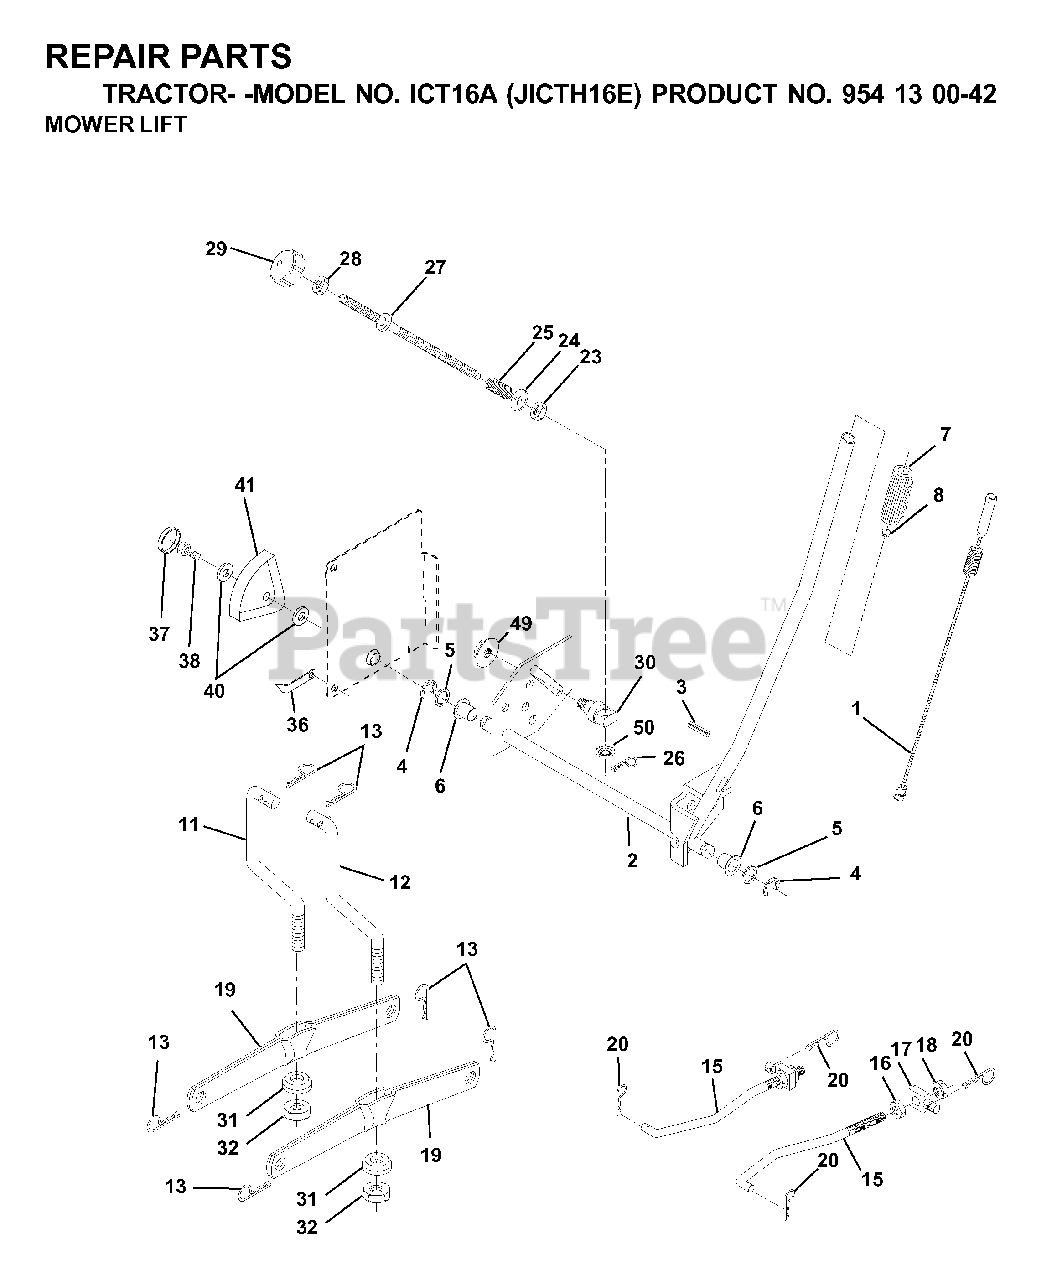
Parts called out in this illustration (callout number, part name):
1	WIRE ASM INNER W/ PLUNGER LT
2	SHAFT ASM R HANDLE
3	PIN GROOVE
4	RETAINING RING LT
6	BEARING.NYLON
7	GRIP HANDLE
8	PLUNGER BUT KIT
11	LINK
12	LINK
13	RETAINER-SPRNG RB
15	LINK.SUSPENSION.FRONT
16	NUT
17	TRUNION
18	NUT
19	ARM.REAR.SUSPENSION
20	SPRING RETAINER
25	SPRING**
26	RETAINER CLIP
27	ROD ADJ LIFT
28	NUT
29	KNOB INF 3/8-16
31	BEARING.PIVOT.LIFT
32	NUT CROWNLOCK 3/8-24
36	POINTER, HEIGHT INDICATOR
37	PLUG,HOLE
38	SCREW 5/16-18X1
41	HEIGHT INDICATOR
49	NUT
50	NUT PUSH M
